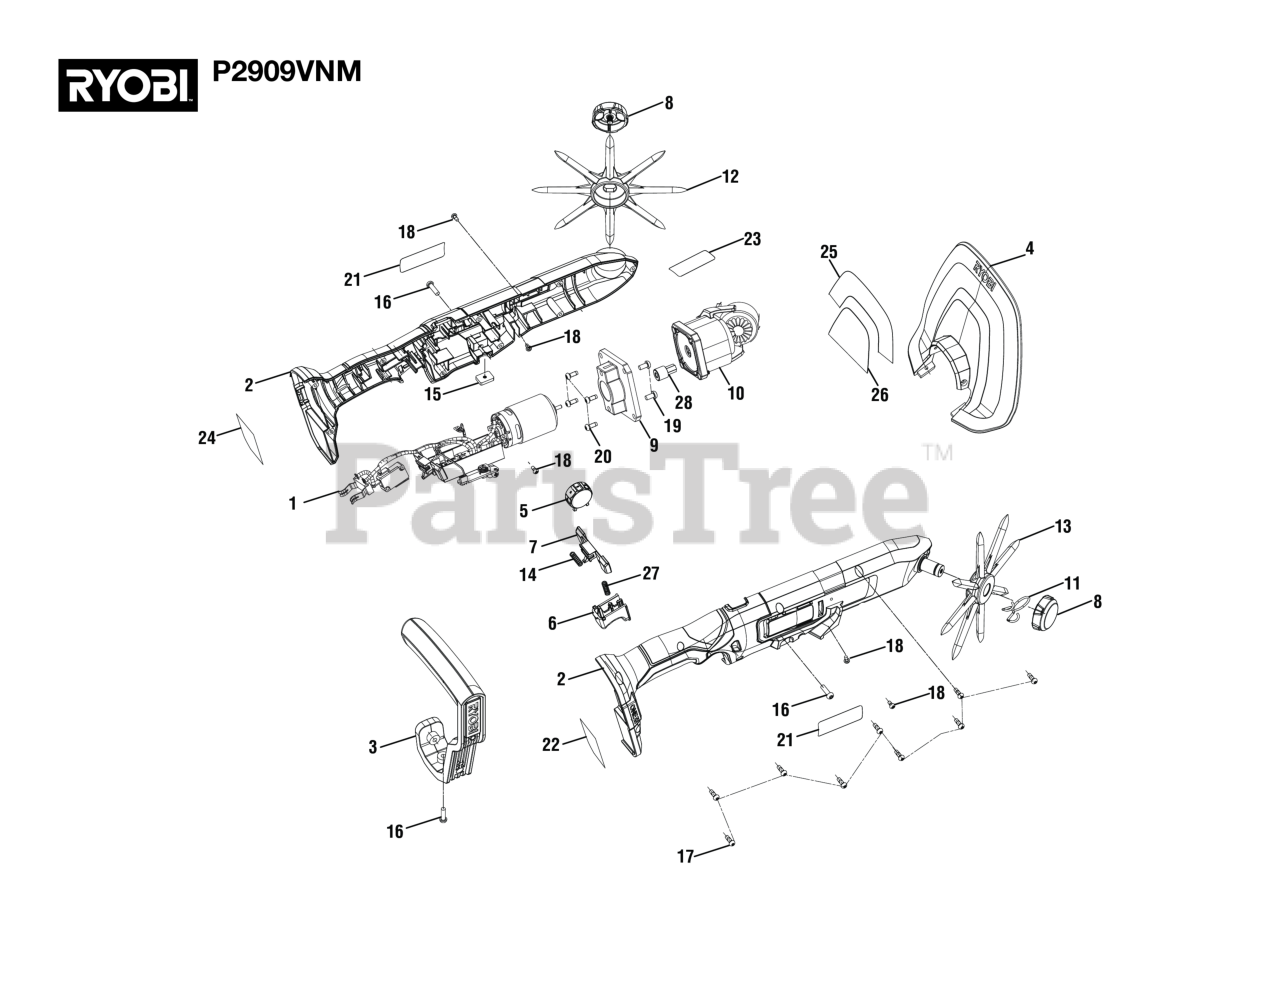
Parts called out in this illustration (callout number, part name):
1	Motor, Switch and Motor Controller Assembly
2	Housing Assembly
3	Assist Handle
4	Guard Assembly
5	Speed Control Knob
7	Safety Lock
8	Quick Release Knob
9	Motor Mount
10	Gear Box Assembly
11	Compression Spring
12	Driving Blade (Left)
13	Driving Blade (Right)
14	Spring (Safety Trigger)
15	SQUARE NUT (M4 X 15 X 10.9)
16	Screw (M5 x 14.5 mm, T20 Torx Pan Hd.)
17	Screw (M3.5 x 10 mm, T10 Torx Pan Hd.)
18	SCREW, CH M3 PH B\L=6MM
19	Screw (M3 x 6 mm, Pan Hd.)
20	Screw, M3x8mm, Steel
21	Logo Label
22	Data Label
23	Warning Label
25	Icon Label
26	Warning Label
27	Trigger Spring
